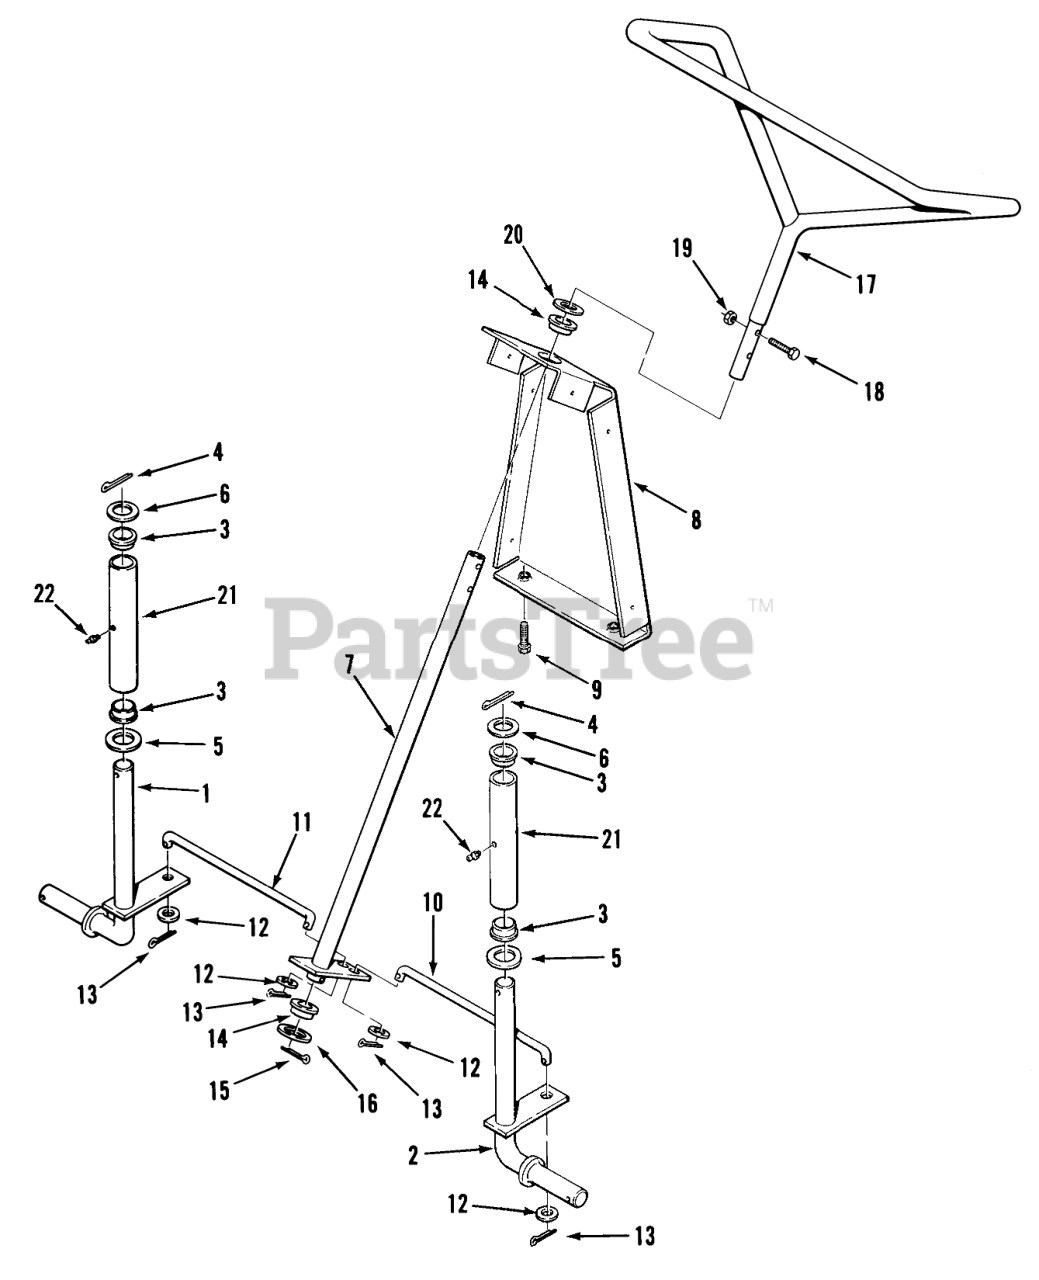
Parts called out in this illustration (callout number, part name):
1	SPINDLE ASSY RH R
2	SPINDLE ASSY LH R
3	BUSHING
4	Cotter Pin
5	Washer
6	WASHER
7	Steering Shaft Assy
8	SUPPORT-STG UPPER B
9	Screw
10	LH TIE ROD R
11	RH TIE ROD R
12	Washer-3/8
13	Cotter Pin
14	BEARING
15	Cotter Pin
16	WASHER-FLAT
17	Steering Wheel
18	Bolt
19	Nut
20	Washer
21	Spindle Tube
22	Grease Zerk
